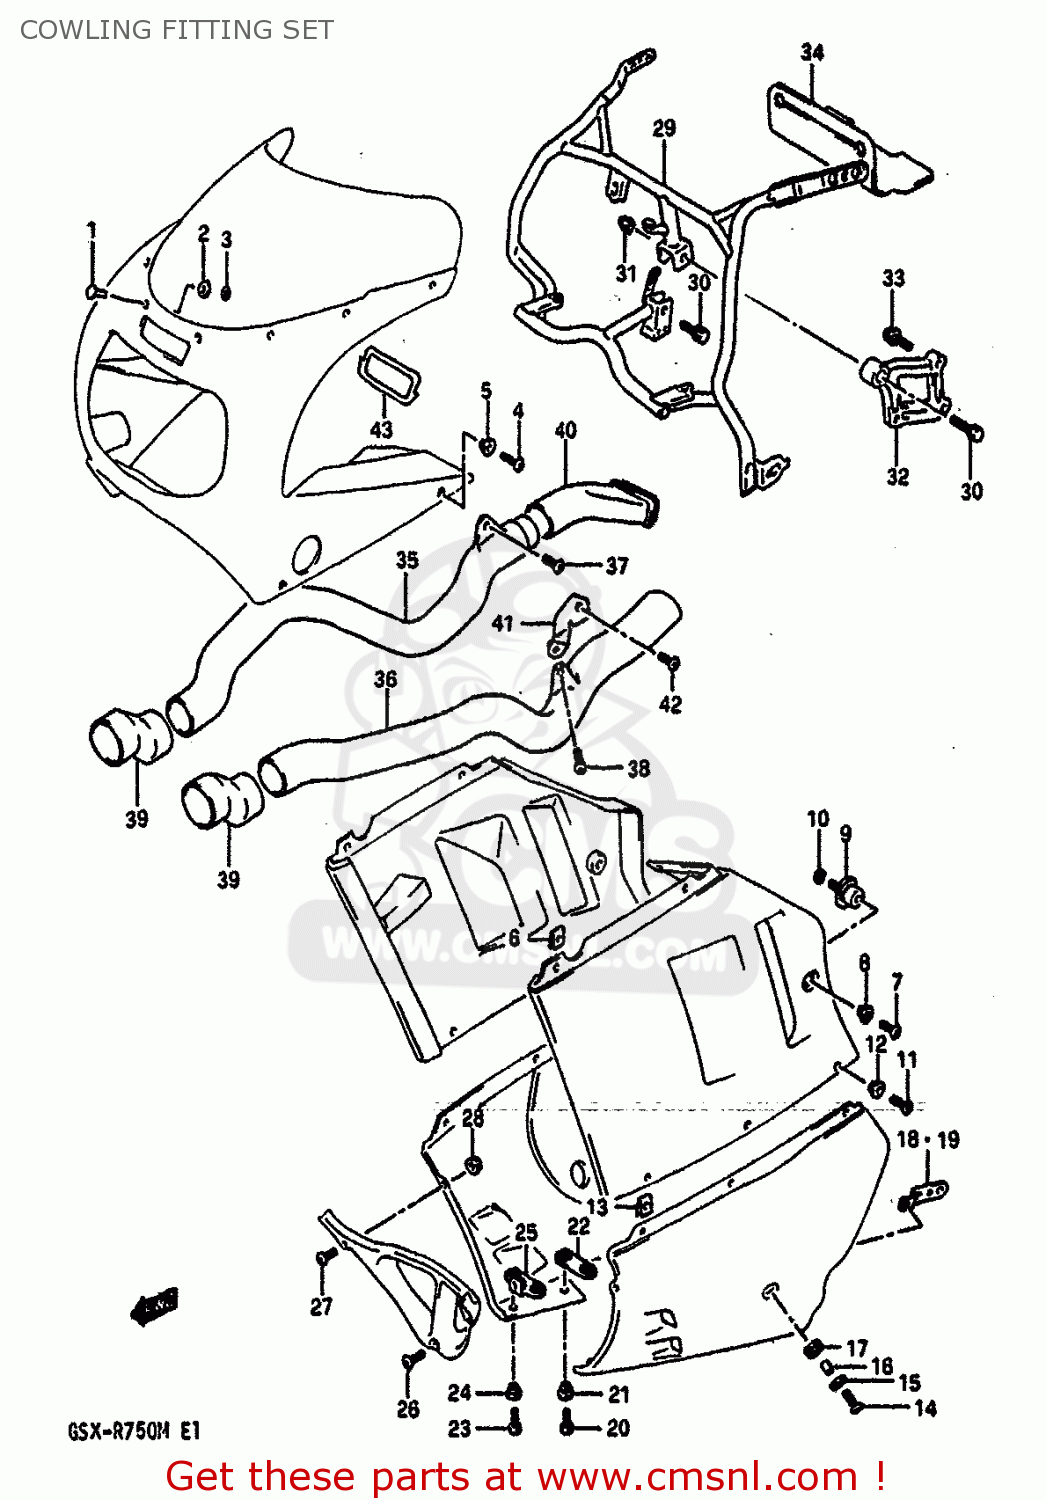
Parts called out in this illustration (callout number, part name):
1	PIN,WINDSCREEN
2	CUSHION
3	NUT
4	SCREW(5X18)
5	WASHER(5.2X14X1.5)
6	NUT,HEADLAMP HOUSING,UPPER
7	SCREW(6X12)
8	WASHER(6.3X16X1.5)
9	CUSHION,COWLING
10	WASHER,LOCK
11	SCREW(5X18)
12	WASHER(5.2X14X1.5)
13	NUT,HEADLAMP HOUSING,UPPER
14	SCREW(6X20)
15	WASHER(6.5X18X1)
16	SPACER
17	CUSHION
18	BRACE,COWLING LWR,R
19	BRACE,COWLING LWR,L
20	SCREW(6X16)
21	WASHER(6.3X16X1.5)
22	BRACE,COWLING LWR COVER RR
23	SCREW(6X16)
24	WASHER(6.3X16X1.5)
25	BRACE,COWLING LWR COVER
26	SCREW(6X16)
27	SCREW(5X14)
28	NUT
29	BRACE,COWLING
30	BOLT, BRACE (8X30)
31	NUT ,8MM
32	BRACE,COWLING CTR
33	BOLT, BRACE CENTER (8X40)
34	SHEET,COWLING HEAT GUARD
35	PIPE,AIR INTAKE,FRONT
36	PIPE,AIR INTAKE FR,L
37	SCREW
38	SCREW 6X12
39	JOINT,AIR INTAKE
40	PIPE,AIR INTAKE RR,R
41	PLATE,AIR INTAKE,LEFT
42	BOLT
43	CUSHION,FR POSITION LAMP
